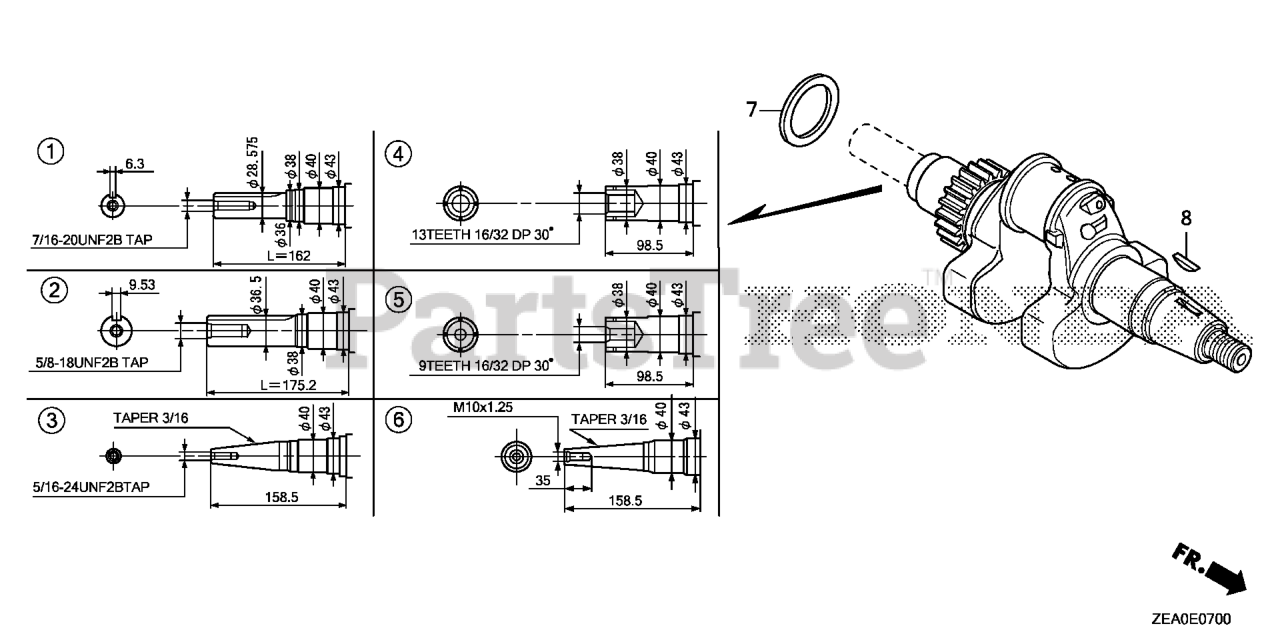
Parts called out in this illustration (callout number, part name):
1	CRANKSHAFT (L=162)
7	WASHER, CRANKSHAFT THRUST
8	KEY, SPECIAL WOODRUFF (25X18)
